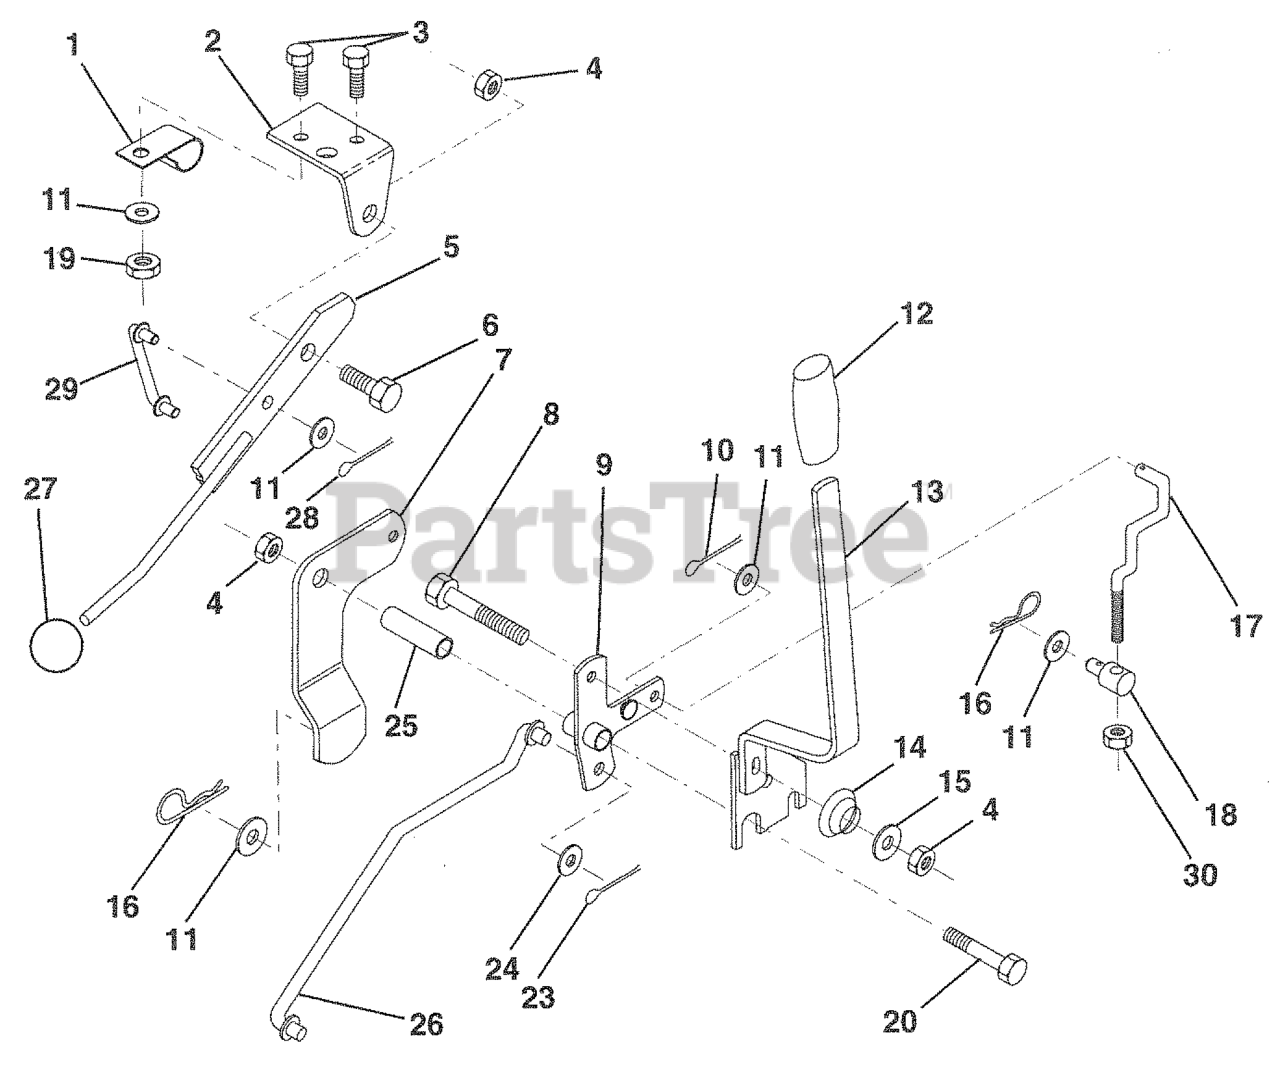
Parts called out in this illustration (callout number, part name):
1	CLIP,INSULATOR
2	BRKT CLUTCH
3	BOLT
5	CLUTCH LEVER ASSY
6	BOLT, SHOULDER LT
7	ASSEMBLY MOWER CLUTCH ARM
9	BELLCRANK,LIFT
10	COTTER PIN
11	WASHER
12	HANDLE GRIP
13	LIFT HANDLE ASSY
14	SPRING COMPRESSIO
15	WASHER T
16	SPRING TI
17	LINK LIFT FRT
18	TRUNION
19	NUT.CROWNLOCK.1/4
23	PIN COTTER
24	WASHER
25	TUBE SPACER
26	ROD,MOWER LIFT
27	KNOB T (3/8 HOLE)
28	COTTER PIN
29	LINK MOWER CLUTCH
30	NUT
